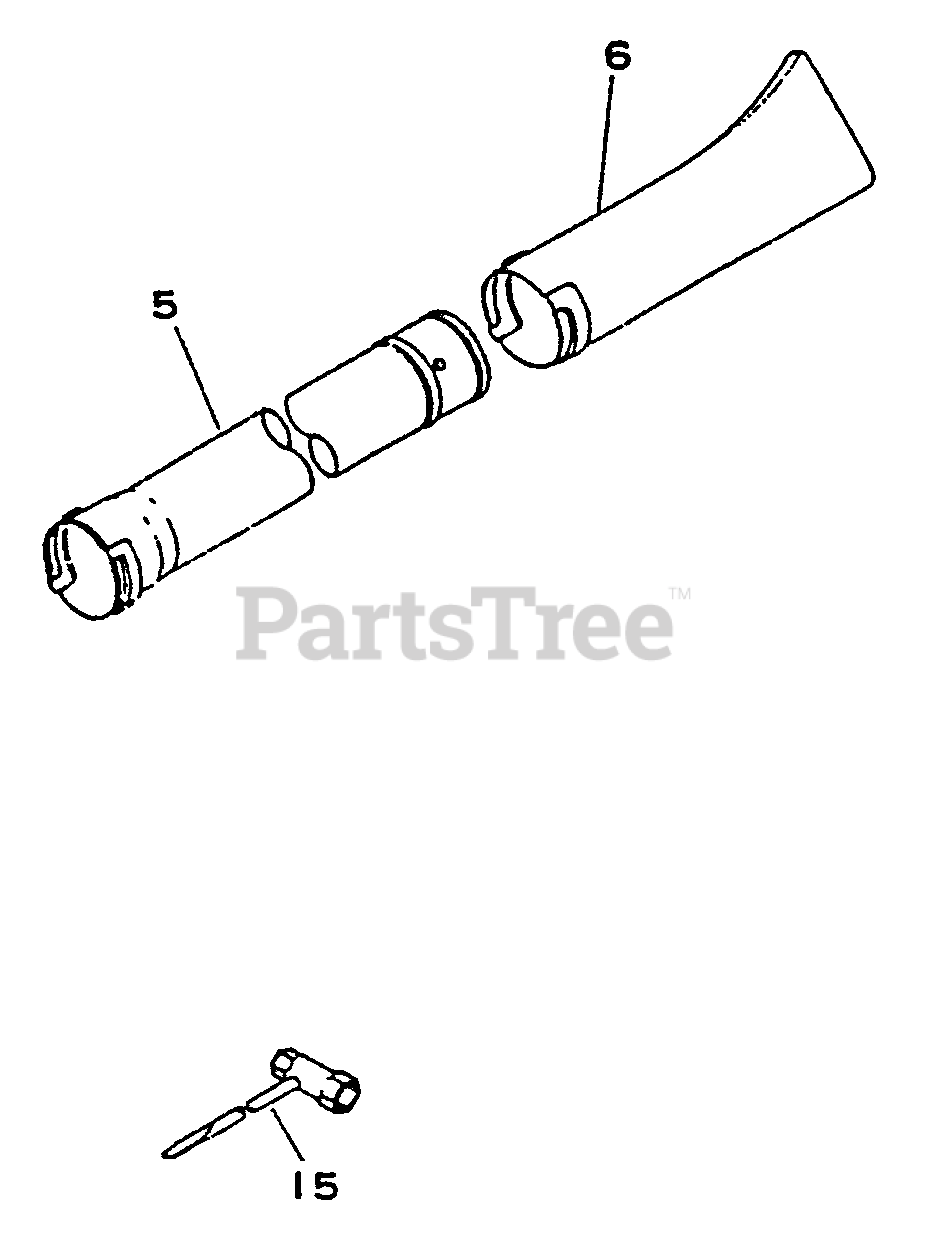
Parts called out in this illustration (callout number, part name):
5	TUBE, BLOWER - STRAIGHT
6	NOZZLE - FAN HEAD
15	T-WRENCH
